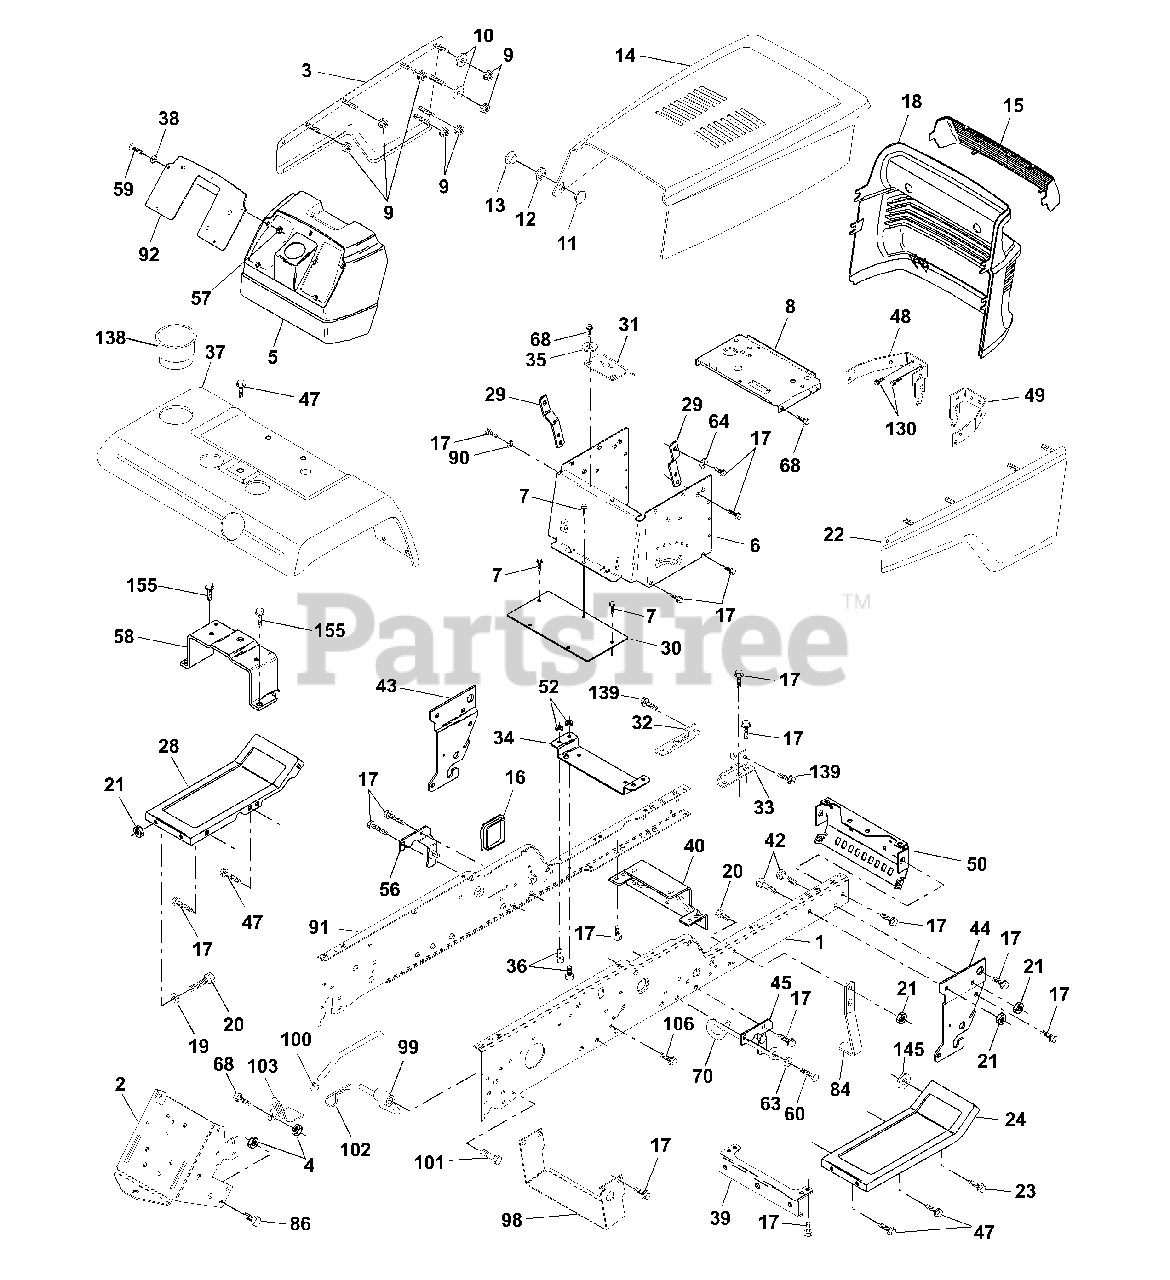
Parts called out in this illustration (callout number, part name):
1	Rail, Frame RH
2	Drawbar, Gt
3	Panel Asm., Side LH
4	Nut, Lock Hex 7/16 Unc
5	Dash, Plastic
6	Dash, 1PCS, Lower
7	Screw, Thd Cut 1/4-20 x 1/2
8	Support, Battery
9	Nut, Pal
10	Washer 9/32 x 1-1/4 x 16
11	Rivet Ratchet Male
12	Washer Nylon
13	Rivet Ratchet Female
14	Hood Asm., Pnt
15	Lens, Headlight Bar
16	Cover, Access
17	Screw, 3/8-16 x 3/4
19	Washer 13/32 x 13/16 x 12 Ga.
20	Bolt, Fin Hex 3/8-16 x 1
21	Nut, Crownlock 3/8-16
22	Panel Asm., Side RH
23	Screw 3/8-16 x 1-1/2
24	Footrest, RH
28	Footrest, LH
29	Bracket, Support Dash
30	Saddle
31	Bracket Supt 1-pc Vgt Steering
32	Bracket, Frame Pivot Lh
33	Bracket, Frame Pivot Rh
34	Bracket, Engine Support Rear
35	Washer 11/32 x 11/16 x 16 Ga.
36	Bolt, Fin Hex 5/16-18 x 3/4
38	Washer, Lock 1/4
39	Bracket, Axle Front
40	Bracket, Support Axle/Engine
42	Bolt Rdhd Sqnk 3/8-16 Unc x 1
43	Bracket, Spnsn Front Lh
44	Bracket, Spnsn Front Rh
45	Bracket Asm., Susp Chassis Rh
47	Screw Thdrol 3/8-16 x 1/2
48	Bracket Asm Hood Lh
49	Bracket Asm Hood Rh
50	Bracket, Chassis Front
52	Nut, Crownlock 5/16-18
56	Bracket Asm., Susp Chassis Lh
57	Nut Keps Blk Hex 1/4-20
58	Bracket Asm., Fender
59	Screw Mach Cr 1/4-20 x 3/4
60	Screw 3/8-16 x 1-1/4
63	Washer 13/32 x 1 x 14 Ga.
64	Washer Serrated Disc 13/32 x 1
68	Screw, 5/16-18 x 1/2
70	Guide, Belt Mid Span
84	Stop, Over Center Mower
86	Bolt, Fin Hex 7/16-14 Unc x 1
90	Washer, Lock External Tooth 3/8
91	Rail, Frame Lh
92	Plate, Silkscreen Dash
98	Bracket Chassis Skid
99	Rod Asm. Bypass
100	Cap By Pass Rod
101	Screw Thdrol. 3/8-16 x 1-3/4
102	Retainer Spring 1"
103	Bracket Lock Bypass
106	Screw Thdrol Hex Head Zinc
130	Screw Hw Hd Hi-Lo #13-16 x 3/4
138	Cupholder
139	Bolt Shoulder 5/16-18
145	Washer Flat 13/32 x 7/8 x 14 Ga.
155	Screw 3/8-16 x 3/4
